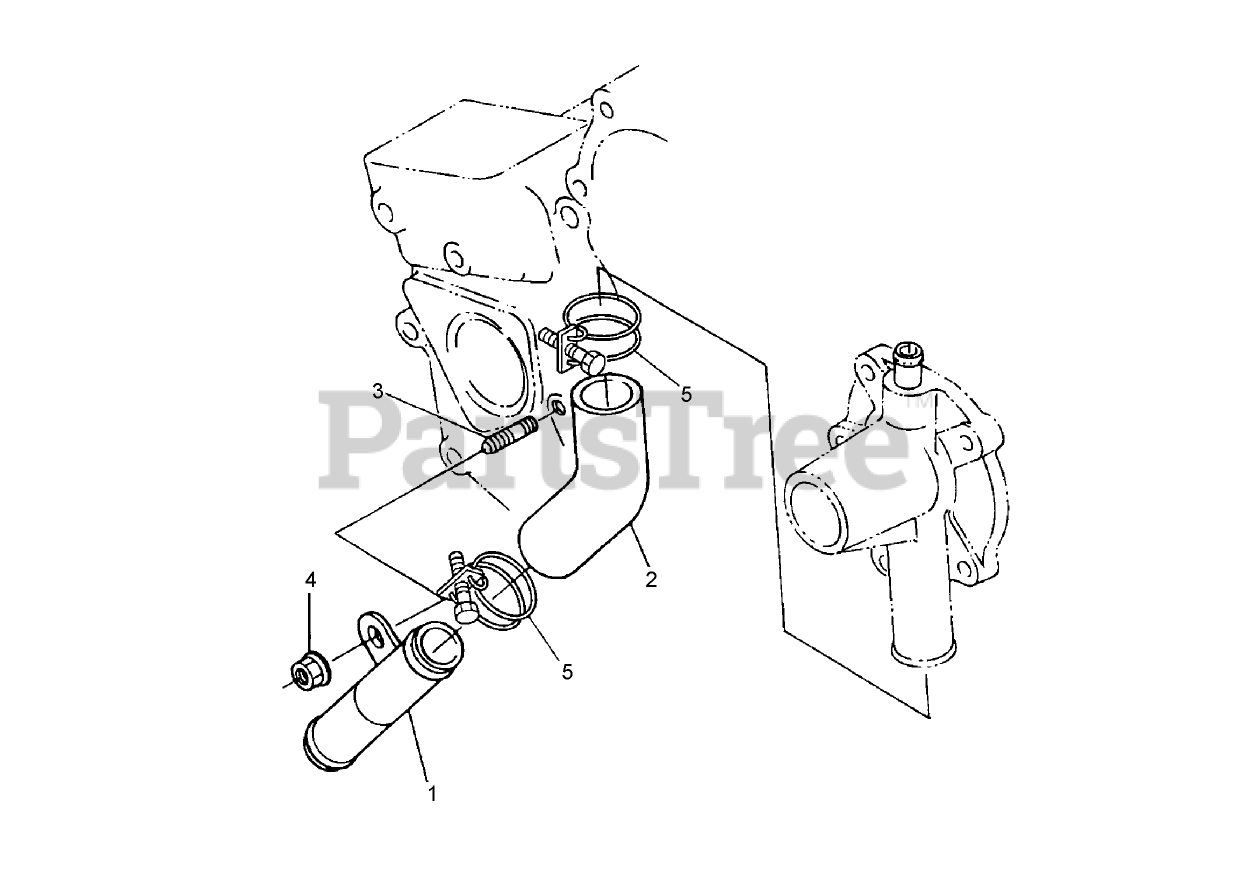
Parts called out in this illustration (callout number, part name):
1	PIPE-WATER
2	HOSE-WATER
4	NUT-FLANGE
5	CLAMP-PIPE
